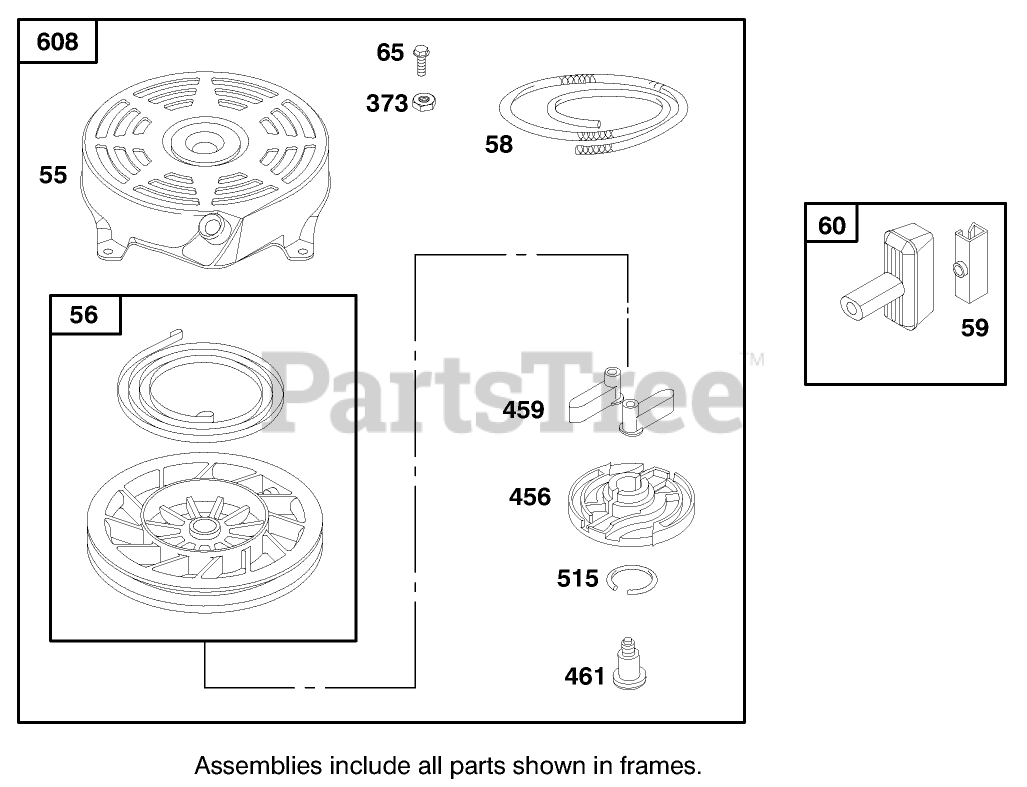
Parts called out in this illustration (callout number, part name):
56	PULLEY-STARTER, REWIND
58	ROPE-STARTER
59	INSERT-HANDLE, REWIND
65	SCREW-HH
373	NUT-HEX
456	RETAINER-STARTER, REWIND
459	PAWL-STARTER
515	SPRING-TORSION
608	REWIND ASM
